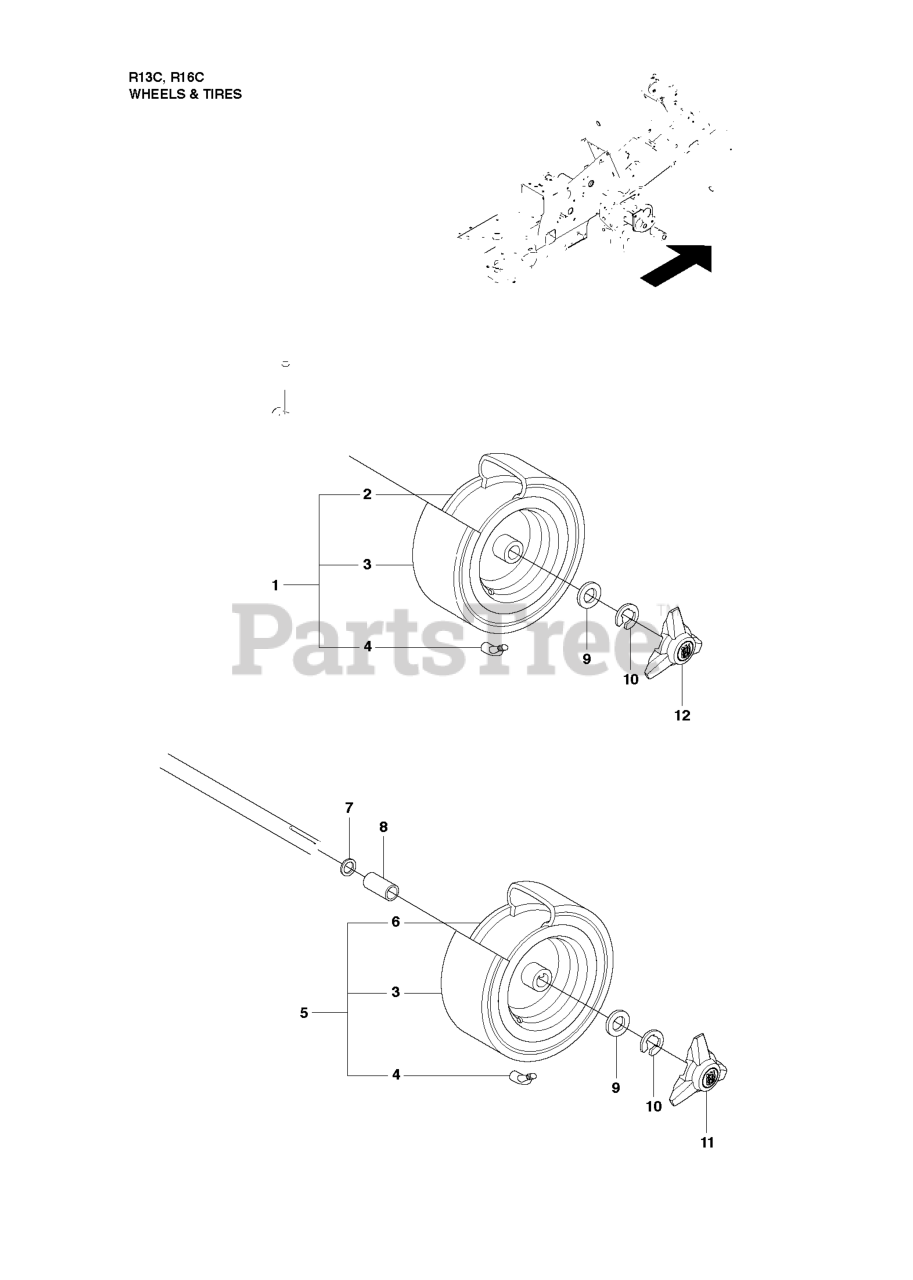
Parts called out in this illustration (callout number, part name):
3	TIRE
4	VALVE
8	SPACE SLEEVE
10	RETAINING RING
